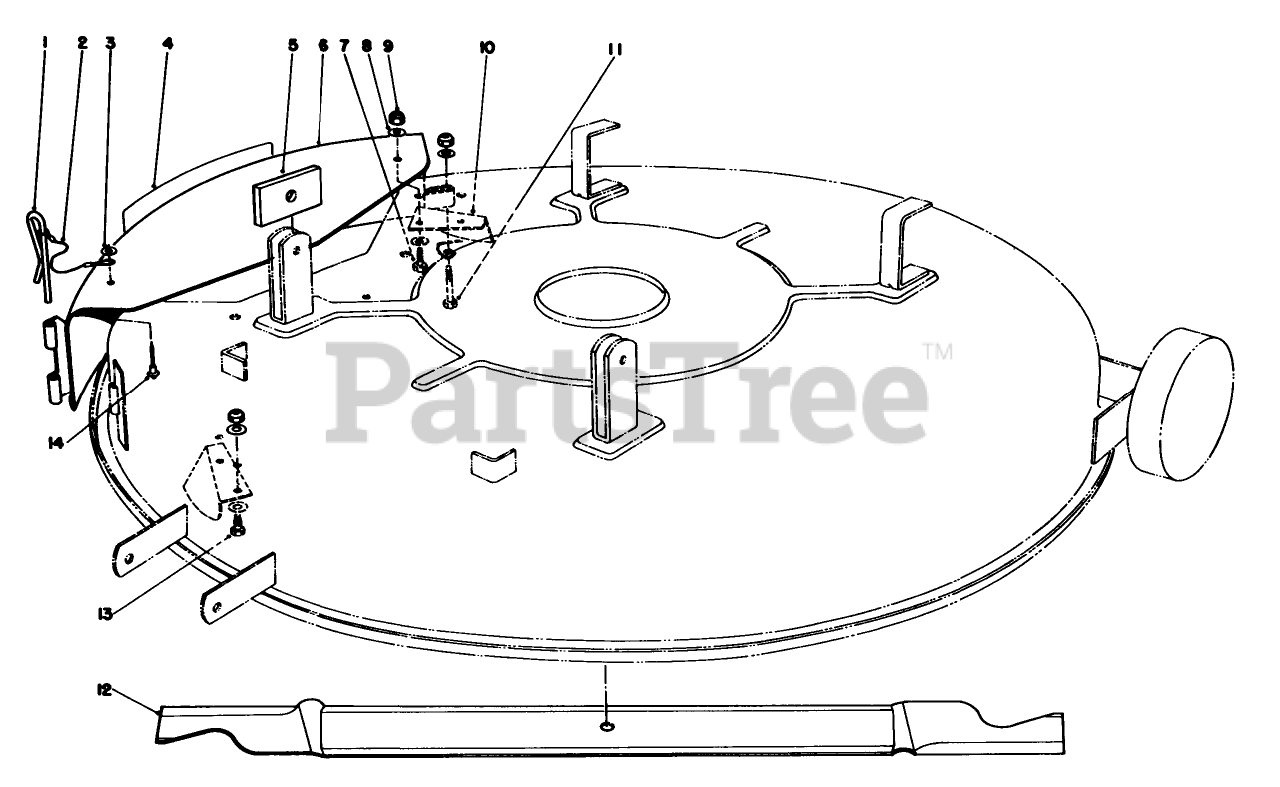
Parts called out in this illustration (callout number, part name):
1	PIN-LOCKING, CHUTE
2	LANYARD
3	WASHER-PLAIN
6	MULCHER COVER ASM (BLACK)
7	SCREW-HH
8	WASHER-PLAIN
9	NUT-LOCK, NI
10	KICKER *B
11	SCREW-HH
13	SCREW-HH
14	RIVET-BLIND
